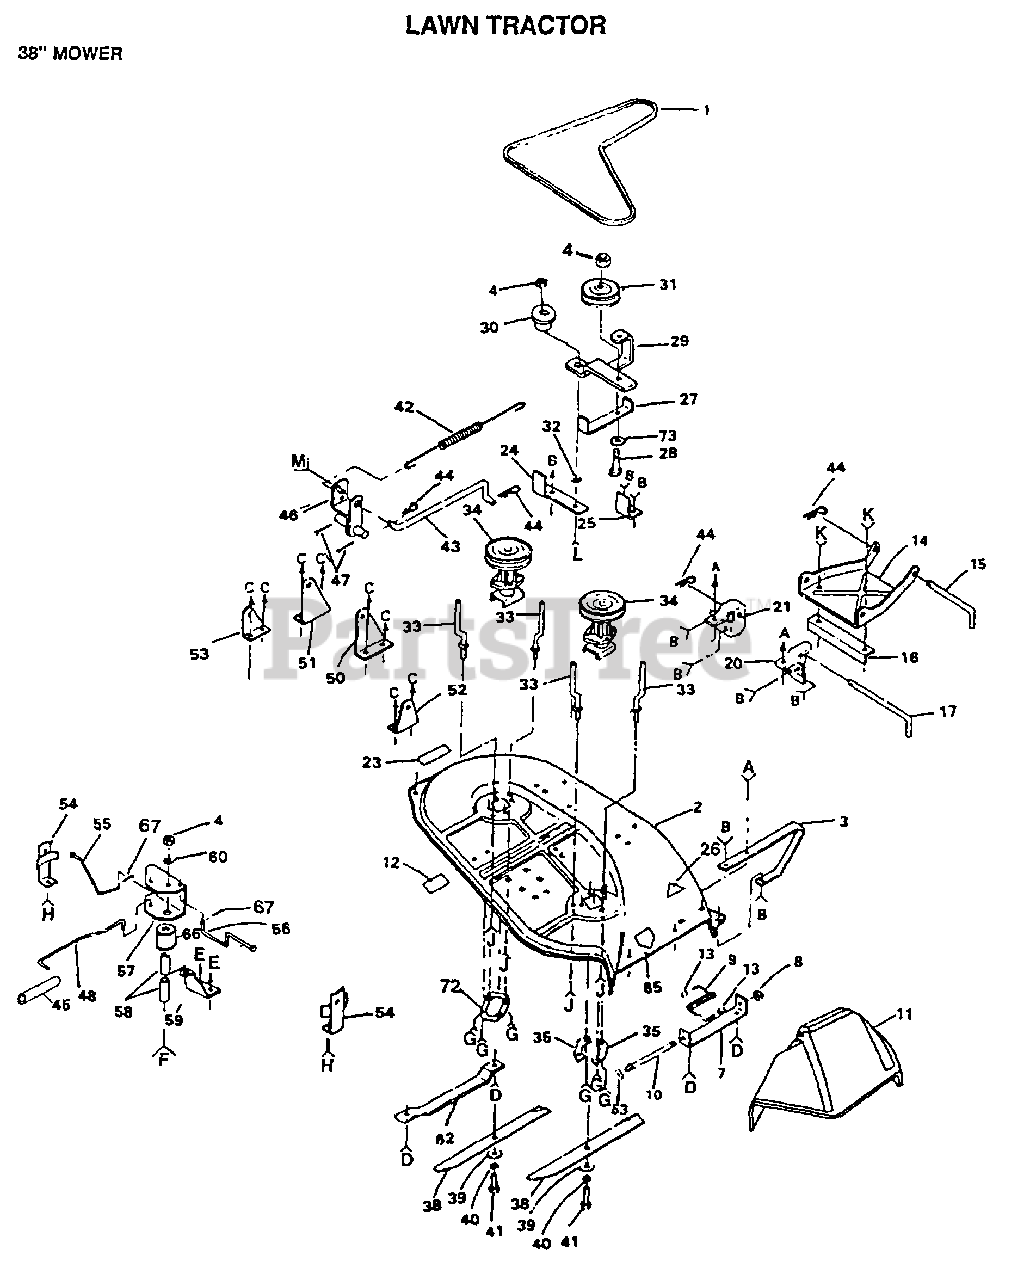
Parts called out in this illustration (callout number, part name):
1	BELT-V.79.1.MWR
6	BOLT
8	NUT PUSH M
10	ROD-HINGE T
11	DEFLECTOR-SHLD T
12	DECAL.LT
13	CAP-SLEEVE LT
14	LINK.PARALLEL
15	"ROD, FRT. PARAL T"
16	LINK STOP
17	HINGE PIN T
20	BRACKET RH LT
21	BRACKET LH T
23	DECAL YT
24	SUPPORT ARM T
25	STOP T
30	SPACER RETAINER
31	PULLEY IDLER
32	"WASHER, WEAR LT"
33	BELT KEEPER LT
34	"JACKSHAFT.38""LT"
35	SUPPORT PLATE LT
38	"BLADE.38"" HI-LI"
39	WASHER
41	BOLT.3/8-24X1-1/2
44	SPRING.RETAINER
45	SPACER T
48	ROD BRAKE LT
52	"BRKT,SUSP RH T"
53	"BRKT,SUSP REAR LH"
54	BRAKE LT
55	"ROD, BRAKE LH LT"
56	ROD BRAKE LT
57	"BRK,BRAKE,PVT LT"
58	SPACER BRAKE LTV
59	BRACKET SUPT LTV
60	WASHER
62	RUNNER-LH M
63	WASHER
65	DECAL WARNING
72	SUPPORT T
73	WASHER
